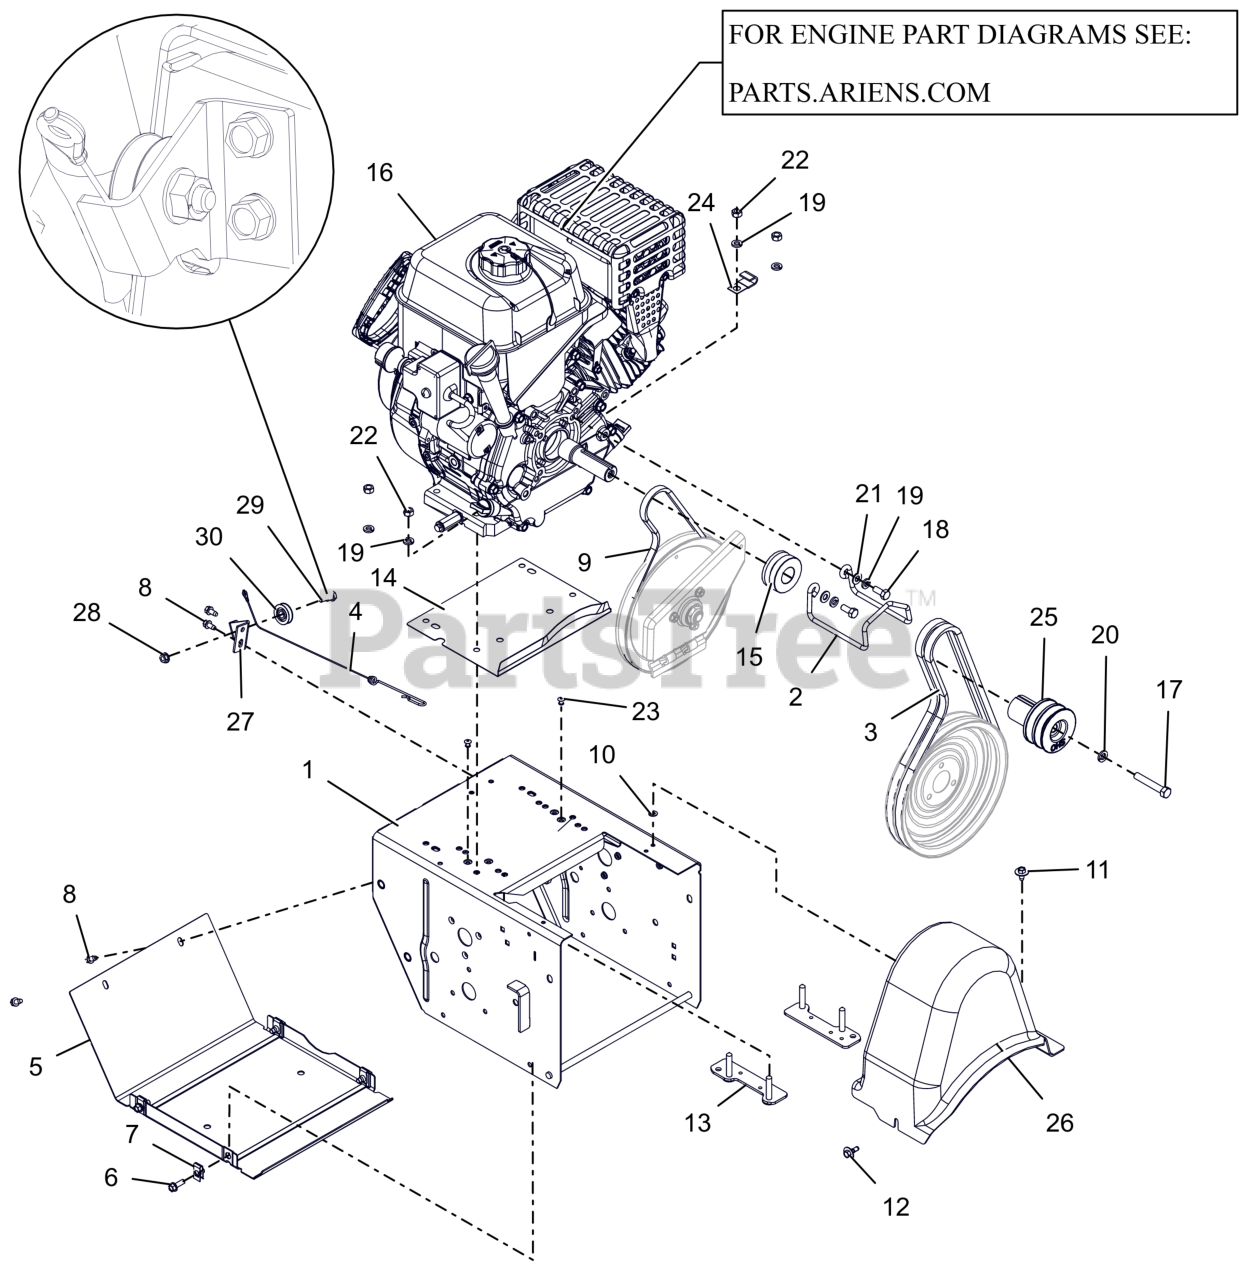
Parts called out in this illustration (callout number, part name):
1	FRAME, MAIN - 14GA DELUXE (ORANGE)
2	FINGER, BELT
3	V-BELT, HA-RAW EDGE (SET)
4	CABLE, LOWER TRACTION,SS & PRO
5	COVER, BOTTOM
6	BLT, HWH .25-20X.75 G5 ZCC
7	NUT-RTNR .25-20X.56
8	SCR-TAP .25-20X.50 HWH ZCC
9	V-BELT, 3L-WRAPPED
10	NUT-PUSH .25X.50 O.D.
11	SCR, TAP .25-20X.50 LG HWH ZCC
12	SCR-TAP .25-20X.5 CAPTIVE
13	STRAP, ENGINE-MEDIUM BLOCK
14	BAFFLE, WATER - LARGE BLOCK
15	SHEAVE, TRACTION (KEYLESS)
16	ENGINE, ARIENS AX291 240V/60W
17	BLT, HEX .38-24X2.25 G5 ZCC
18	BLT, HEX .31-24X.750 G5 ZCC
19	WSHR, LK-HVY .312X.097 ZCC
20	WSHR,LK-REG .375X.094 ZCC
21	WSHR,FLT .344X.688X.065 ZCC
22	NUT, HEX .312-18 ZCC
23	RVT, POP .1875 ZCC
24	J-CLAMP
25	SHEAVE,ATTACHMENT-SHO 2 GRV
26	COVER, BELT-LARGE
27	BRACKET, CABLE PULLEY
28	NUT-LK-TOP-FLG .250-20 GF ZCC
29	BOLT, SHLDR -.375 X .375 X .25-20
30	PULLEY, CABLE
